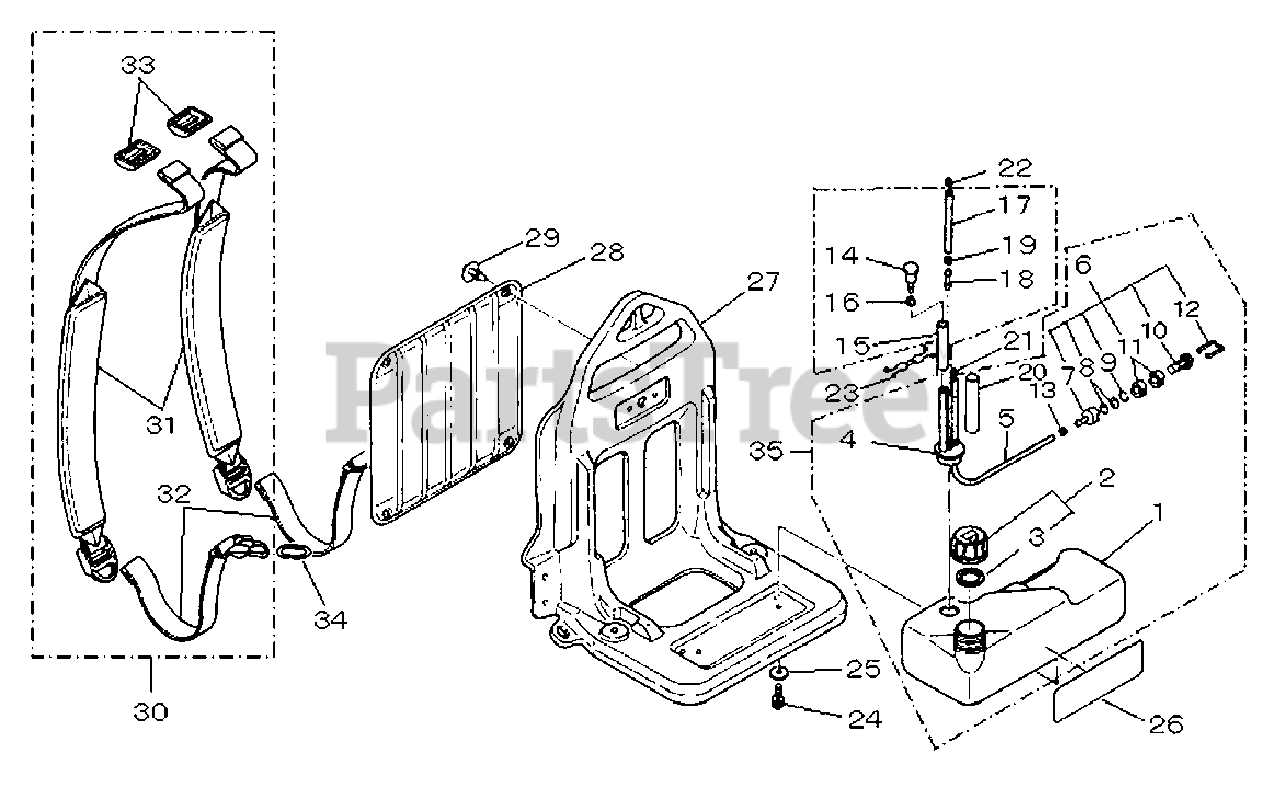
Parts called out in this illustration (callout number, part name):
2	CAP ASSY
3	GASKET, CAP
4	PIPE ASSY
5	PIPE - FUEL
6	FILTER, FUEL
7	WEIGHT, FUEL FILTER
8	SCREEN, FILTER
9	RING, RETAINING
10	CASE, FILTER
11	FILTER, FUEL
12	CLIP, FILTER
13	RING, RETAINING - 6
14	VENT, FUEL TANK
15	TUBE
16	RING, RETAINING - 6
17	TUBE - 5X3X110
18	CONNECTOR, PIPE
19	RING, RETAINING - 6
20	SLEEVE X12 X X11 X L70
21	CLIP - SPRING
22	CLIP - SPRING
23	CLIP
24	SCREW - 5X14
25	COLLAR
26	LABEL - TRADE
27	FRAME
28	PAD
29	CLIP
30	HARNESS ASSY
31	STRAP, BACKPACK
32	STRAP
33	BUCKLE
34	HOOK, SPRING
35	FUEL TANK ASSY
